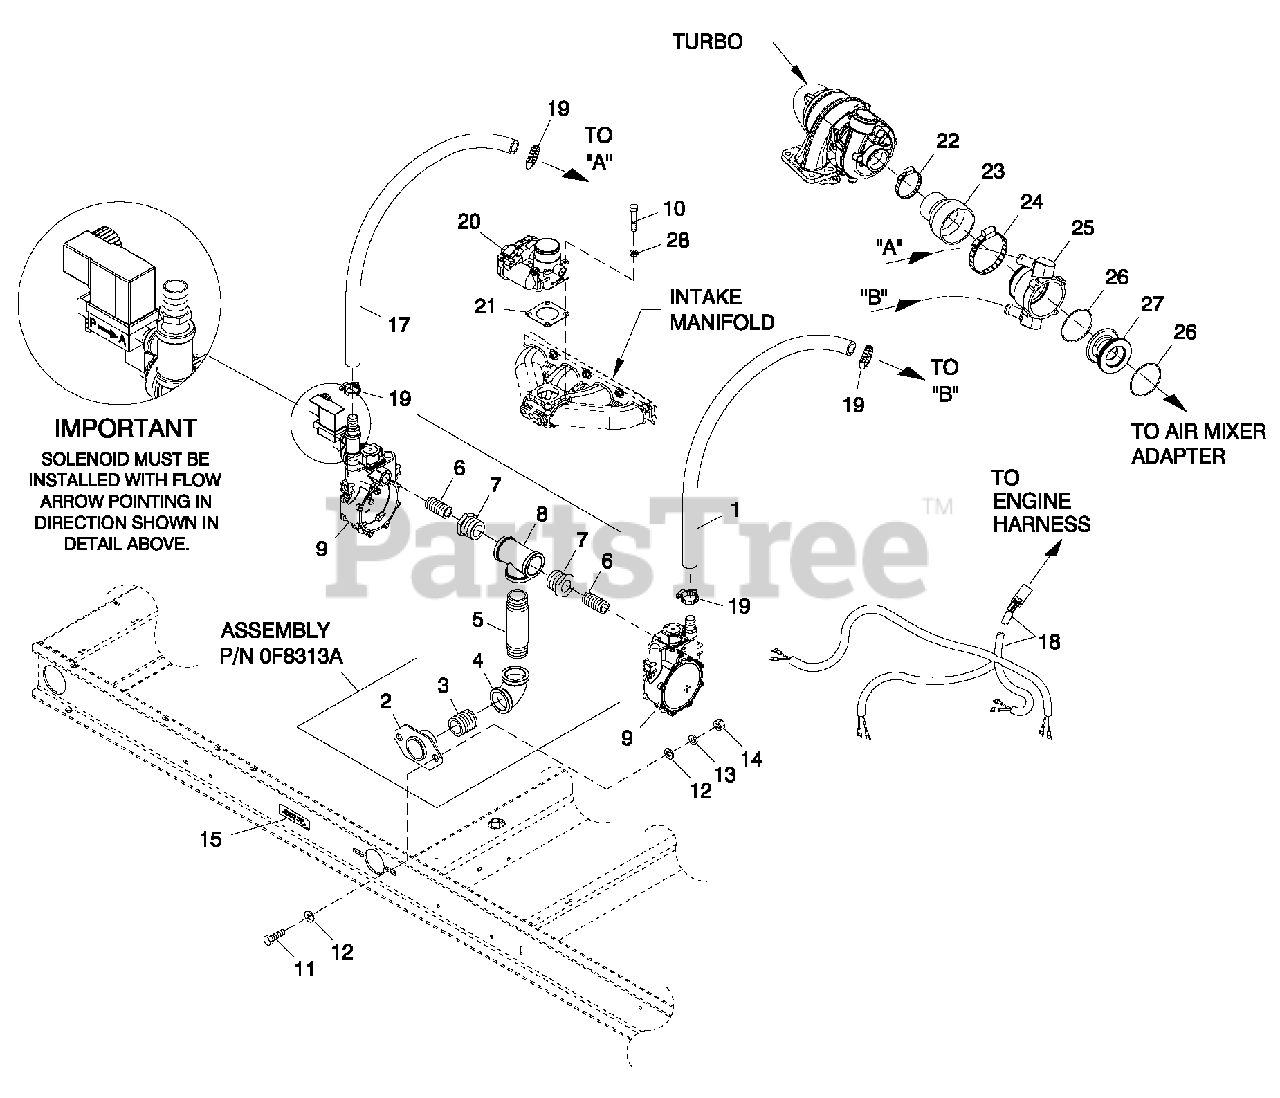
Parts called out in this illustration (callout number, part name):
1	HOSE 3/4 ID SAE-30R2 (43"LG)
2	FLANGE FUEL INLET
3	NIPPLE CLOSE 1.25 NPT X 1.625
4	ELBOW 90D1-1/4 NPT
5	NIPPLE PIPE 1.25 NPT X 5.5 BLIRN
6	NIPPLE CLOSE 3/4X1.375
7	BSHG RDCR HEX1-1/4-3/4
8	PIPE TEE 1-1/4 NPT
9	REG ASSY 2.4L 60KW NG CPL
10	SCREW SH C M6-1.0X45 C12.9
11	SCREW HH C '8-1.25 X 25 C8.8
12	WASHER FLAT 3/8-M10ZINC
13	WASHER LO CK M8-5/16
14	NUT HEX M 8-1.25 G8 CLEAR ZIN C
15	DE CAL, UL FUEL RATING
17	HOSE 3/4 ID SAE-30R2 (43" LG)
18	HARN FUEL JUMPER DUAL REG
19	CLAMP HOSE #10 .56-1.06
20	ACTUATOR BOSCH 40 GOVERNOR
21	GASKET BOSCH 32
22	CLAMP HI TORQUE 1.75-2.625
23	REDU CER RUBBER 3.0"-2.00"
24	CLAMP HI TORQUE 2.75 - 3.625
25	MIXER 40/60MM A CTUATOR ASSY
26	O-RING 2-3/4X3/32X2-15/16
27	VENTURI THROTTLE 32MM
28	WASHER LO CK M6-1/4
